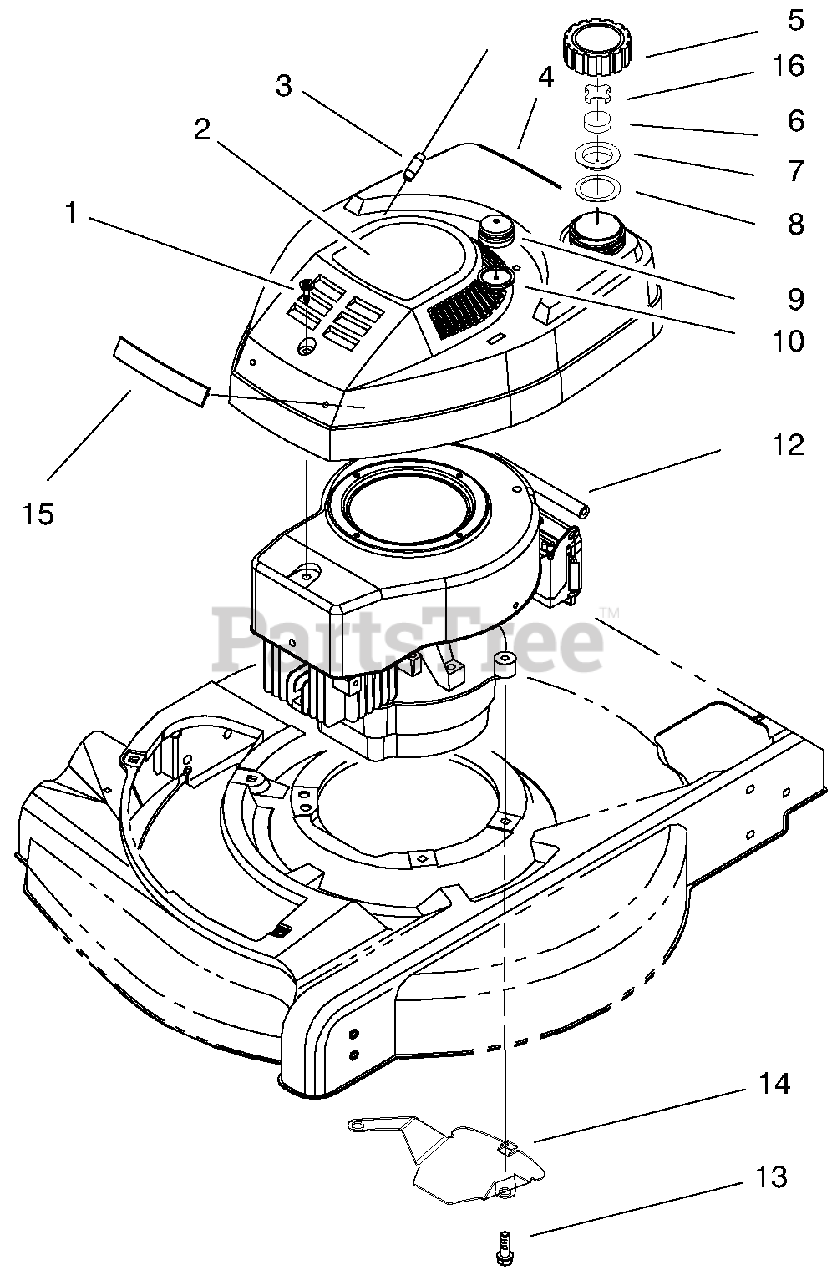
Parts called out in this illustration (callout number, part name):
1	Screw-Sems
2	Decal-Recoil
3	Stop-Rope
4	Tank & Shroud
5	Gas Cap Assembly (Incl. Ref. #6-8, & 16)
6	Baffle-Foam
9	Bulb-Primer
10	Body-Primer
12	Line-Gas
13	Screw-Engine
14	Shield-Grass
15	Applique-Shroud
16	Baffle-Gas Cap
